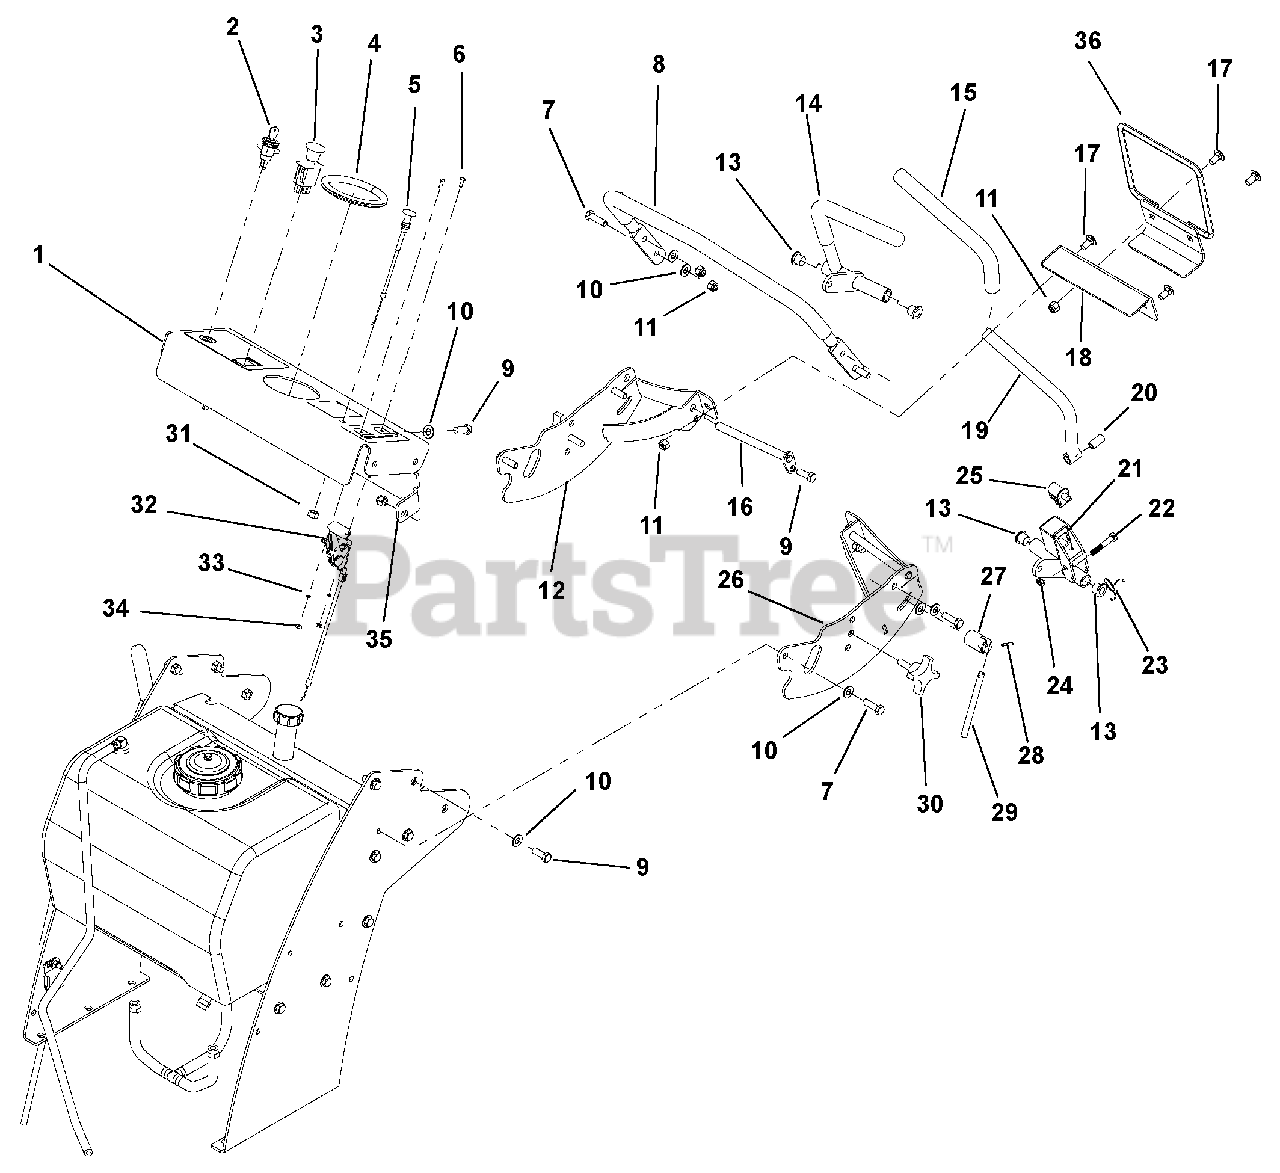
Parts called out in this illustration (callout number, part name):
1	ASSY, CONSOLE W/DECALS
2	SWITCH, TWO POSITION KEY
3	SWITCH, PTO ENGAGEMENT
4	TRIM, RUBBER EDGE 12"
5	CABLE, CHOKE 48"
6	SCREW, #8-32 X .500 RD HD MACH Y
7	BOLT, 3/8-16 X 1.25 HEX 5 Y
8	HANDLE, LOOP HYDRO
9	BOLT, 3/8-16 X 1.00 HEX 5 Y
10	WASHER, .406 X .813 X .065 FLAT Y
11	LOCKNUT, 3/8-16 NYLOC Y
12	WLDT, RH CONTROL MOUNT
13	BRG, FLG .500 X .625 X .500 BRNZ
14	WLDT, RH DRIVE LEVER
15	GRIP, CONTROL
16	WLDT, PIN AND LOCK
17	BOLT, 3/8-16 X 3/4 C
18	DRIVE ARM BACK PLATE
19	WLDT, LH DRIVE LEVER
20	SPACER, .330 X .500 X .980
21	WLDT, LH HANDLE MOUNT
22	BOLT, 5/16-18 X 1.75 HEX 5 Y
23	SPRING, TOR 1.00 X .062 Y
24	LOCKNUT, 5/16-18 NYLOC Y
25	SWITCH, SEAT OVER RIDE (N.O.)
26	WLDT, LH CONTROL MOUNT
27	BASE, LOCK LEVER Y
28	PIN, SPRING
29	LEVER, LOCK Y
30	KNOB, 3/8 X 1.25 - 4 PRONG
31	NUT, 3/8-24 STD HEX Y
32	CABLE, THROTTLE - 49.5
33	WASHER, #8 MED SPRG LOCK Y
34	NUT, 8-32 STD HEX Y
35	ASSY, HANDLE BRACE W/DECALS
36	WLDT, REVERSE INDEX BAR
